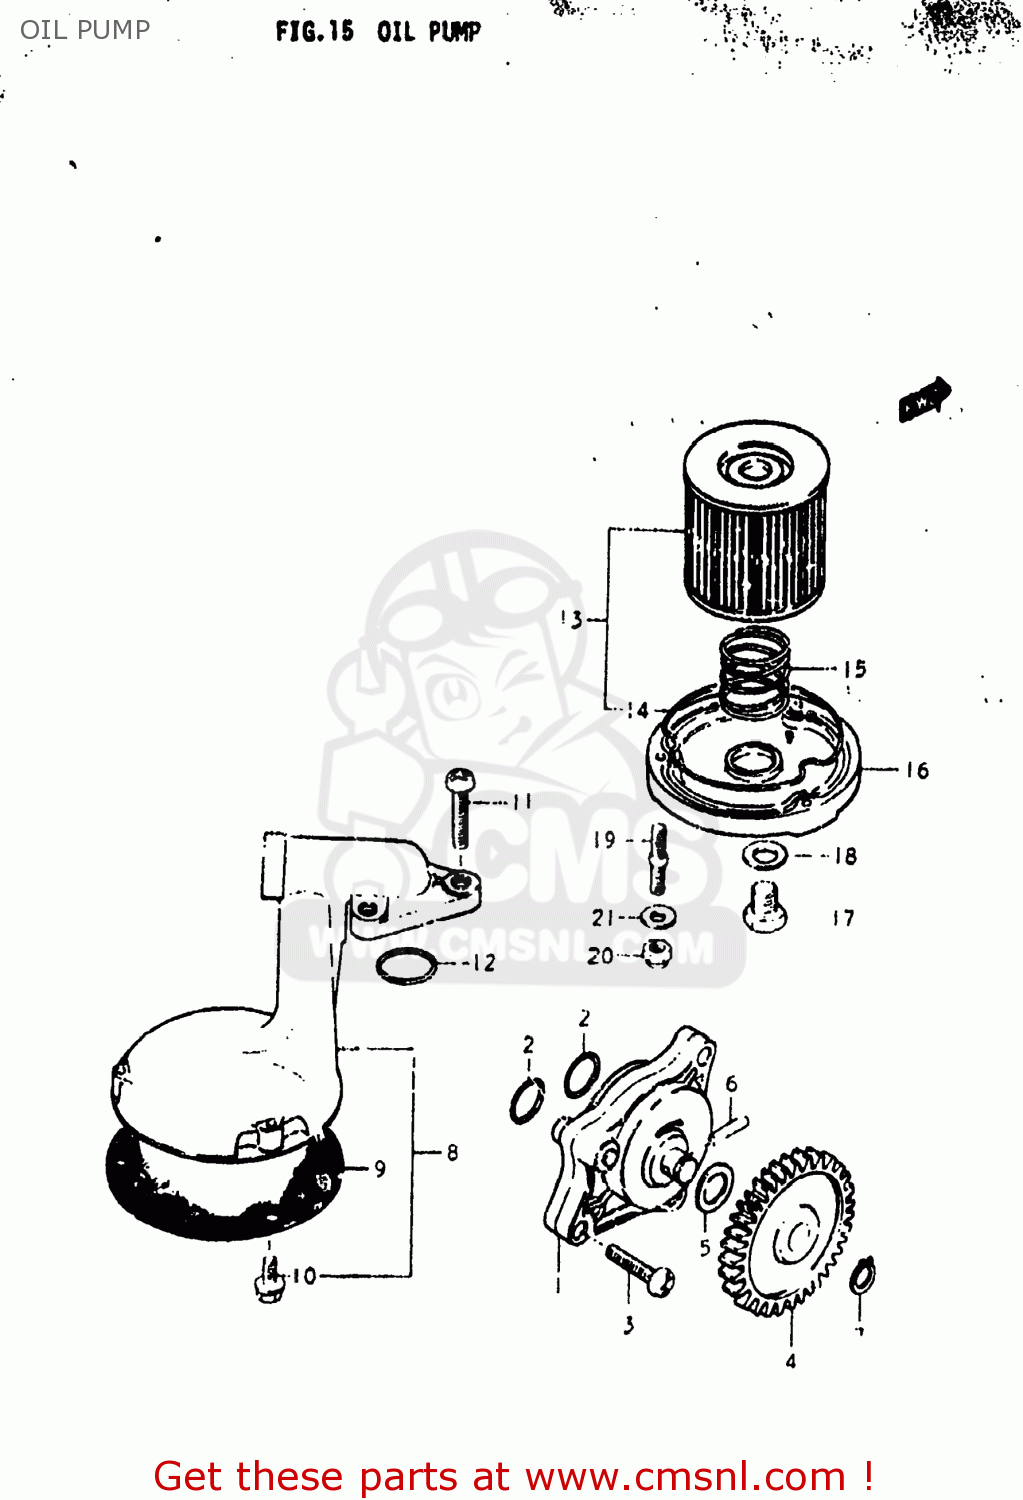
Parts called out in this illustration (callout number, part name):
1	PUMP ASSEMBLY,OIL
2	O RING(D:1.9,ID:13)
3	SCREW
4	GEAR,OIL PUMP DRIVEN
5	SHIM
6	PIN(4X15.8)
7	CIRCLIP
8	STRAINER,ENGINE OIL
9	NET
10	BOLT
11	SCREW
12	O RING(D:2.4,ID:15.8)
13	ENGINE OIL FILTER SET
14	O RING,OIL FILTER CHAMBER CAP
15	SPRING
16	CAP,OIL FILTER
17	PLUG
18	GASKET(10X14X3.6) (NAS)
19	STUD 6X20
20	NUT C,XC
21	WASHER
